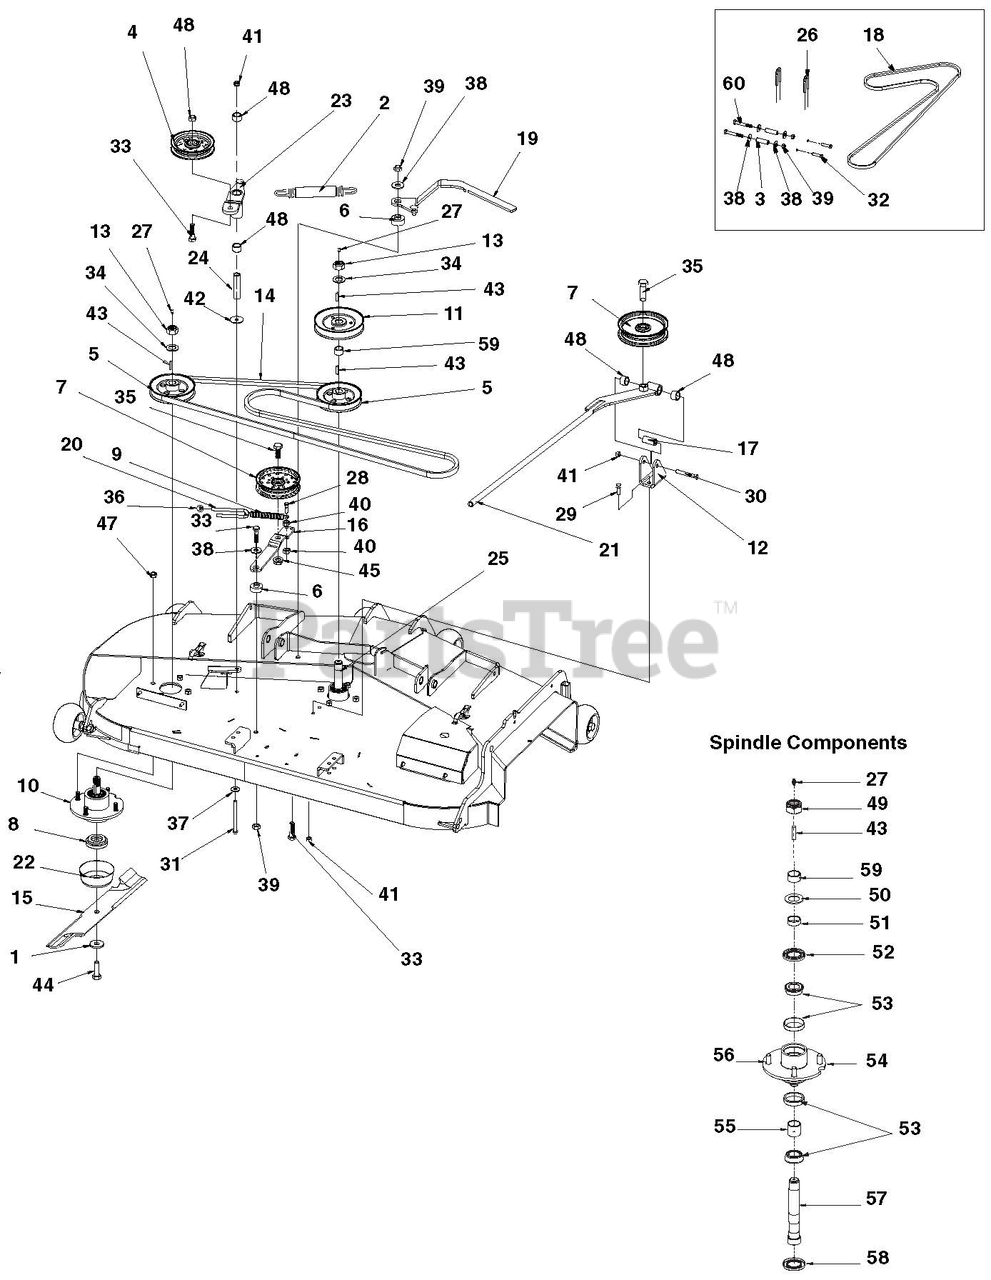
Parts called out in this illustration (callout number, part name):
1	WASHER, M14XM40XM4.5 FLAT Y
2	SPRING, EXT 1.18X.177X7.50 Y
3	TUBE, RD .750 X.125W X 2.469
4	PULLEY, V-BELT 5.00X.510 W/BRG
5	SHEAVE, 5.00 SPINDLE (1.00ID)
6	SPACER, .516 X .750 X .853 Y
7	PULLEY, FLAT 5.00X.635 W/BRG
8	SPCR, BLADE
9	SPRING, EXT .750X.125X4.50 Y
10	ASSY, SPINDLE 1"SHORT SHFT S/O
11	PULLEY, V-BELT 6.57X1.00 W/KEY
11	PULLEY, V-BELT 7.21X1.00 W/KEY
12	PLATE, PIVOT ANCHOR BENT
13	LOCKNUT, 3/4-16 CROWN PL
14	BELT, HB 123.0 OC PES OHR
14	BELT, HB 131.0 EL AMD
15	BLADE, 20.940 X 1.00 LIFT
15	BLADE, 23.00 X 2.5 1.00 LIFT
16	ARM, BELT TENSIONER
17	SPANNER
18	BELT, HB 114.9 EL AMD
19	WLDT, TENSION ARM
20	U-BOLT, RD .63X4.50X3/8-16SP Y
21	ASSY, OFFSET ARM
22	CAP, SPINDLE
23	ASSY, DECK IDLER
24	TUBE, RD .750 X .156 X 3.05
25	ASSY, SPINDLE 1" LONG SHFT S/O
26	U-BOLT, RD 1.00X3.00X3/8-16 Y
27	FTG, 1/4-28 STRGT GREASE ZERK
28	BOLT, 5/16-18X1.25 HEX 5 Y
29	BOLT, 3/8-16X1.00 HEX 5 Y
30	BOLT, 3/8-16X2.50 HEX 5 Y
31	BOLT, 3/8-16X4.25 HEX 5 Y
32	BOLT, 7/16-14X1.75 HEX 5 Y
33	BOLT, 1/2-13X1.75 HEX 5 Y
34	WASHER, 1.062X1.75X0.100 Y
35	BOLT, 5/8-11X1.50 HEX 5 Y
36	NUT, 3/8-16 STD HEX GR5 Y
37	WASHER, .375 REG FLAT Y
38	WASHER, .500 REG FLAT Y
39	LOCKNUT, 1/2-13 CROWN Y
40	LOCKNUT, 5/16-18 WHIZ Y
41	LOCKNUT, 3/8-16 CROWN Y
42	WASHER, .375X1.50X.063 FLAT Y
43	KEY, .250 X .250 X 1.00 SQ
44	BOLT, 9/16-12X1.75 HEX 8 Y
45	LOCKNUT, 5/8-11 WHIZ Y
46	LOCKNUT, 7/16-14 WHIZ Y
47	NUT, 7/16-20 HEX GR5 Y
48	BRG, SLV .753X.878X.750
49	NUT, 1-14 THIN PATTERN NYLOCK
50	WASHER, 1.062X1.75X0.100 Y
51	BSHG, 1.00 X 1.25 X .438
52	SEAL, UPPER SPINDLE
53	BRG ASSY, 1IN DIA SPINDLE
54	CASTING-MOWER SPINDLE 3.31 LG
55	SPACER, BEARING
56	BOLT, 7/16-20X1.22 SPC 5 Y
57	SHAFT, BLADE SPINDLE 1" SHORT
57	SHAFT, BLADE SPINDLE 1" LONG
58	SEAL, BRG 1.00 ROLLER
59	SPACER, ?1.01 X ?1.25 X .635 Y
60	BOLT, 1/2-13X3.50 HEX 5 Y
61	SPINDLE BEARING KIT
